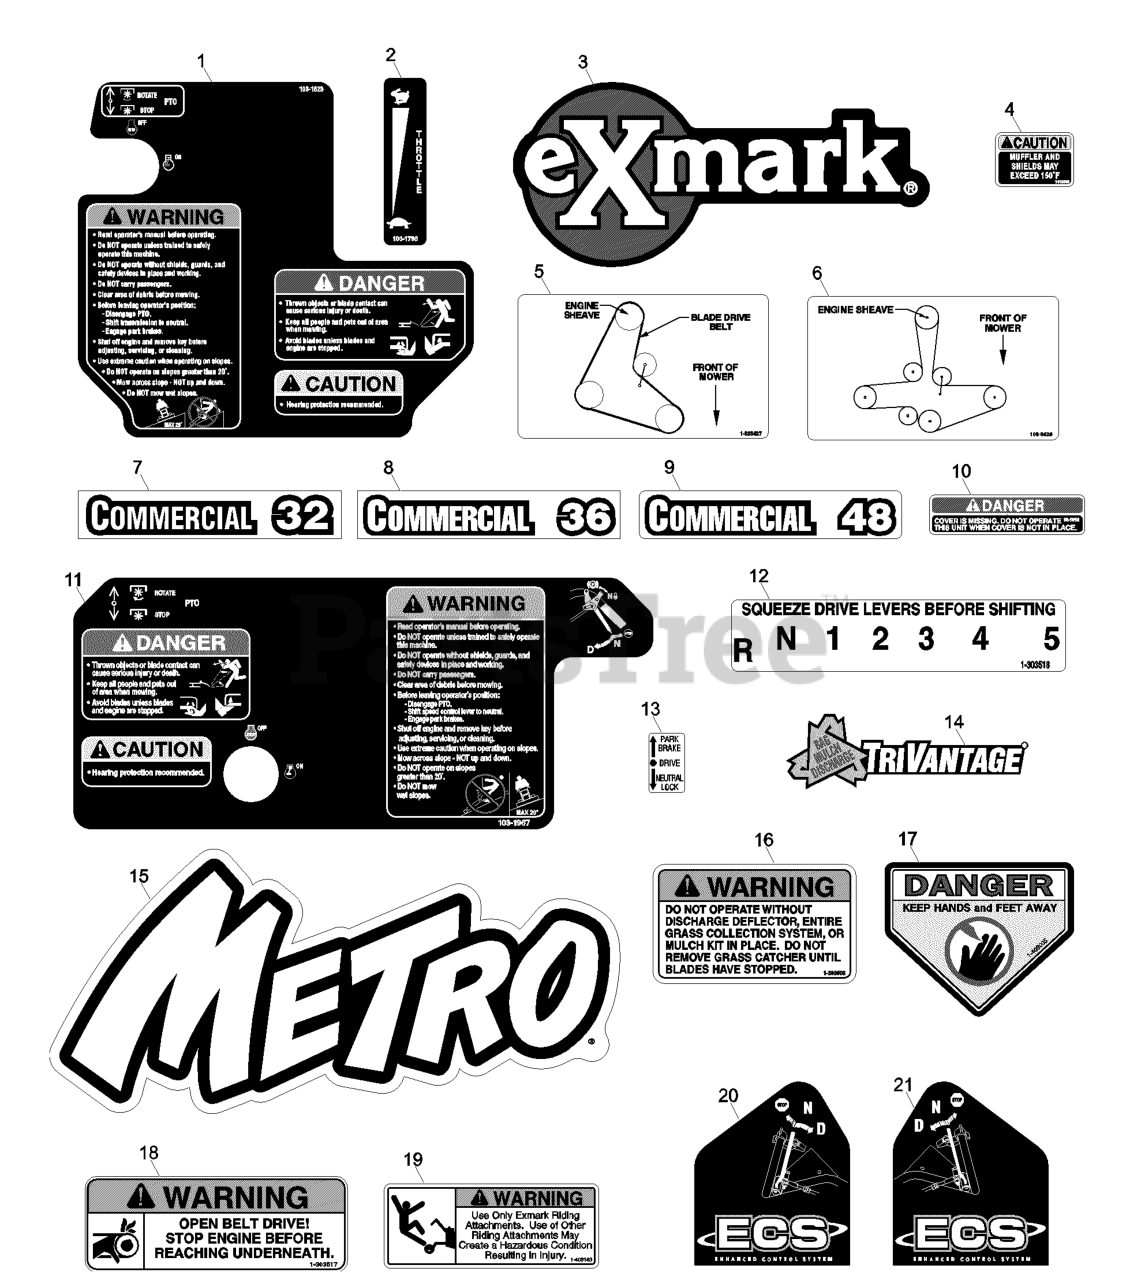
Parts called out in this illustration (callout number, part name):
1	DECAL,METRO ECS CONSOLE
2	DECAL,THROTTLE ONLY
3	DECAL,EXMARK LOGO
5	DECAL,BELT ROUTING 32/36
6	DECAL,BELT ROUTING
7	DECAL,COMMERCIAL 32
8	DECAL,COMMERCIAL 36
9	DECAL,COMMERCIAL 48
10	DECAL-COVER, MISSING
11	DECAL,CONSOLE
12	DECAL,SHIFTER
13	DECAL,NEUTRAL/BRAKE
15	DECAL,METRO MODEL
16	DECAL-WARNING, DISCHARGE
17	DECAL-DANGER
18	DECAL,BELT DRIVE
19	DECAL,SULKY WARNING
20	DECAL,RH ECS INSTRUCTION
21	DECAL,LH ECS INSTRUCTION
